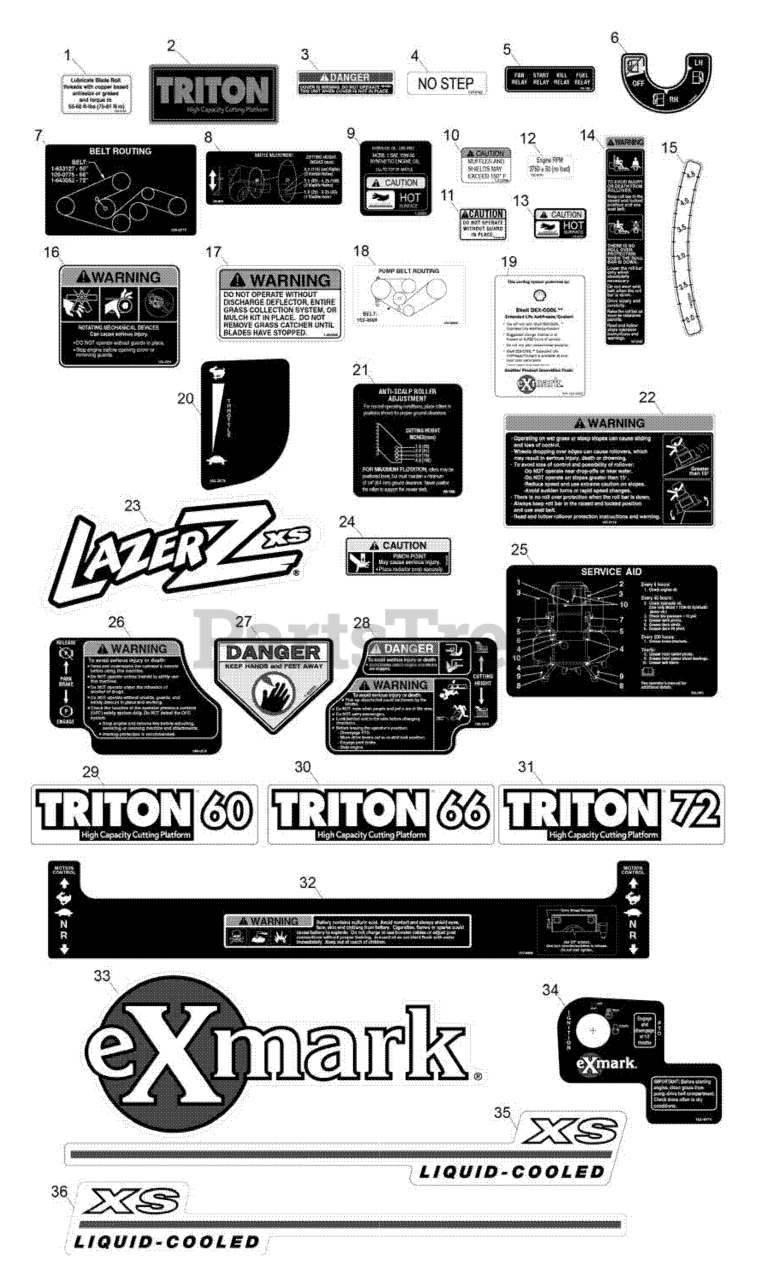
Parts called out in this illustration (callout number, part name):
1	DECAL,BOLT TORQUE
3	DECAL-COVER, MISSING
4	DECAL,NO STEP
5	DECAL,RELAY
6	DECAL-VALVE, FUEL
7	DECAL,BELT ROUTING
8	DECAL,BAFFLE ADJUSTMENT
11	DECAL-GUARD
13	DECAL-CAUTION
14	DECAL-WARNING, FOLDING RO
15	DECAL-HEIGHT, DECK
16	DECAL,WARNING
17	DECAL-WARNING, DISCHARGE
18	DECAL,PUMP BELT ROUTING
19	DECAL,SHELL COOLANT
21	DECAL,ANTISCALP
22	DECAL-WARNING
23	DECAL,LAZER XS MODEL
24	DECAL,RADIATOR ASSEMBLY
25	DECAL,SERVICE AID
26	DECAL,PARK BRAKE
27	DECAL-DANGER
28	DECAL,DECK HEIGHT
29	DECAL,TRITON 60
30	DECAL,TRITON 66
31	DECAL,TRITON 72
32	DECAL-CONSOLE, TOP
33	DECAL,EXMARK
34	DECAL,IGNITION/PTO
35	DECAL,HOOD LXS LC LH
36	DECAL HOOD LXS LC RH
